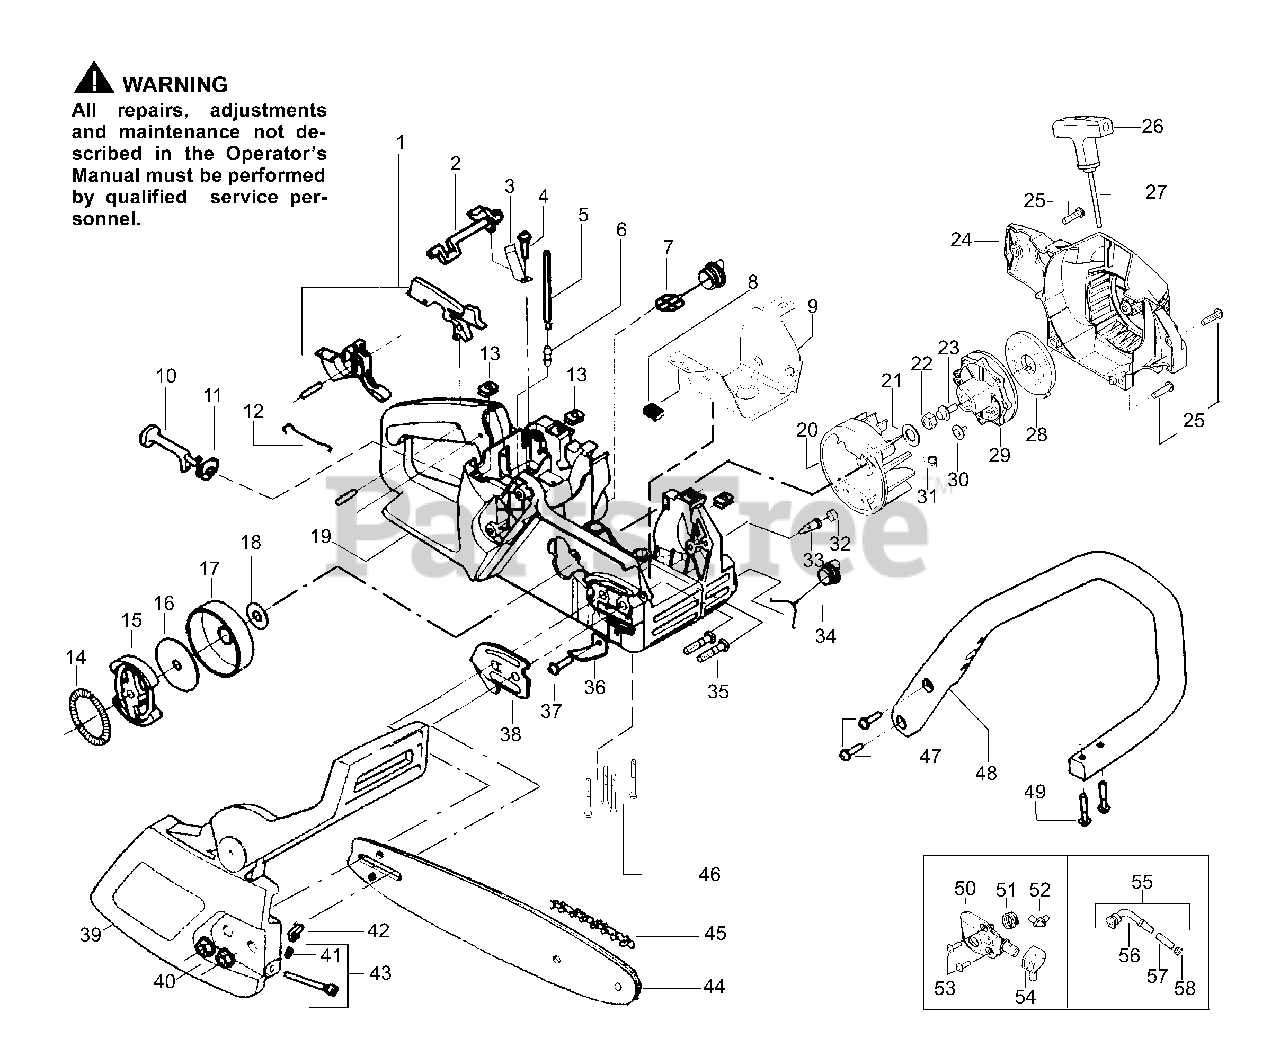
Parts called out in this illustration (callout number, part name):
1	Trigger & Lockout Kit
2	Switch Lever
3	Switch Spring
5	Fuel Line Kit (Large)
6	Fitting -Fuel line
7	Fuel Cap Ass'y.
8	Clip -"U"
9	Shield -Heat
10	Lever-Choke
11	Grommet-Choke lever
12	Wire-Throttle
13	Nut-Speed
14	Spring -Clutch
15	Assy.-Clutch
16	Washer-Clutch
17	Drum Assy. W/brg.
18	Washer -Thrust
19	Kit -Chassis Assy.
20	Flywheel Ass'y.
21	Washer-Flywheel
22	Nut-Flywheel
24	Fan Housing
26	Starter Handle
27	Rope Kit
28	Starter Spring
29	Starter Pulley
31	Spring -Starter Dog
32	Plug -Bronze Vent
33	Check Valve
34	Oil Cap Ass'y.
35	Bolt -Bar
36	Chain Catcher
38	Plate-Bar Mounting
39	Assy.-Chain Brake
40	Nut-Bar Mounting
41	Retainer-Bar Adjust
42	Pin-Bar Adjust
43	Kit-Bar Adjust
45	Chain-18"
48	Front Handle
50	Kit-Oil Pump
51	Gear-Worm Spring
52	Elbow-Oil Pickup
54	Seal Block
55	Oil-Pickup Ass'y.
56	Oiler Pickup
57	Oil Filter
58	Plug-Oil Filter
